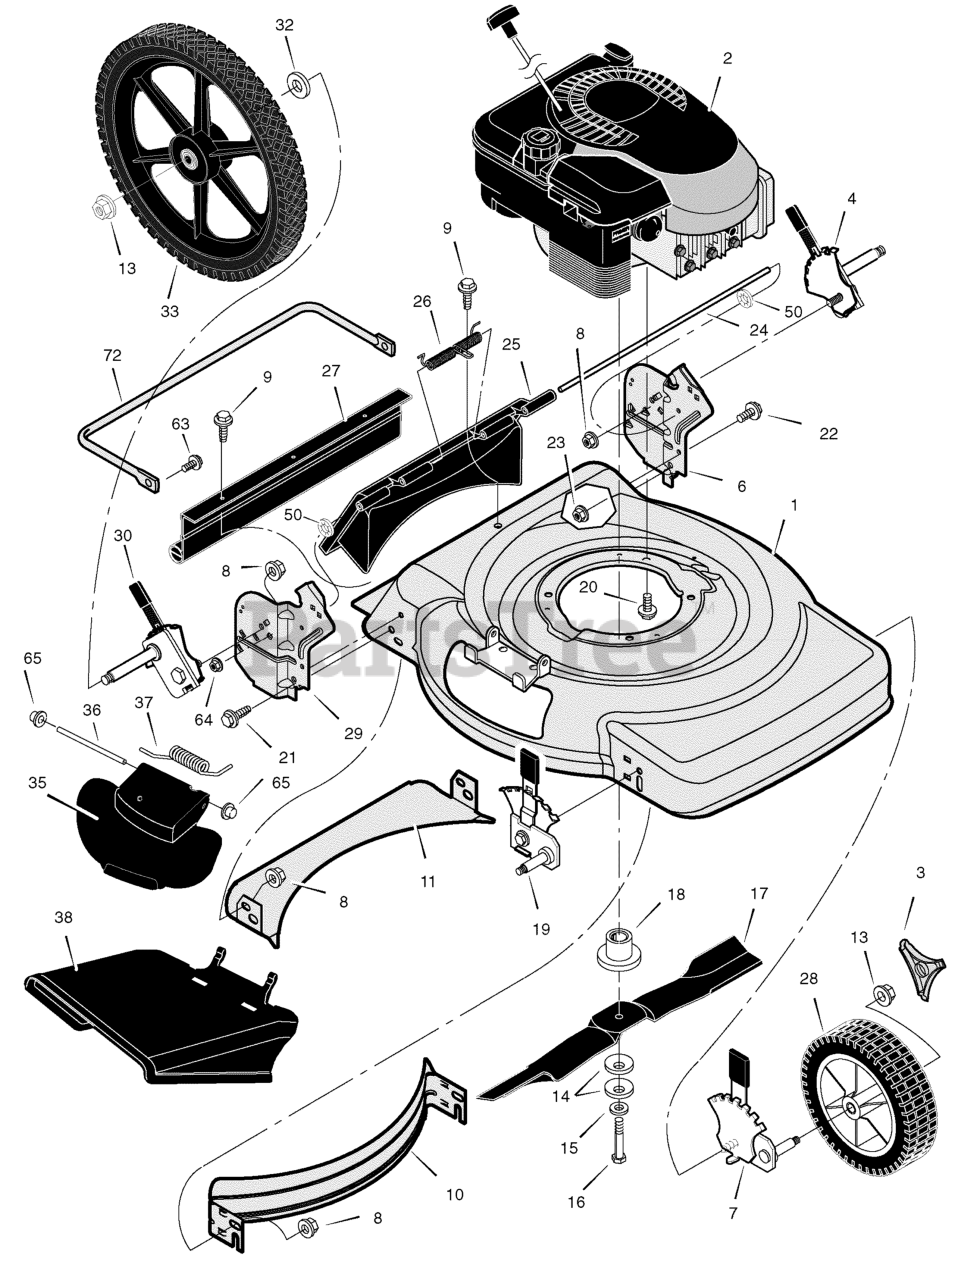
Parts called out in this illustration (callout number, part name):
1	Housing
2	Engine *
3	Cap, Hub (Gray)
4	Adjuster, Left Rear Height
6	Bracket, Left Handle
7	Adjuster, Left Front Height
8	Nut, Flange
10	Baffle, Front
11	Baffle, Rear *
13	Nut, Flange
14	Washer, Belleville
15	Washer
18	Adapter, Blade
19	Adjuster, Right Front Height
20	Bolt, Engine
21	Bolt
22	Bolt
23	Nut, Flange
24	Rod, Pivot
25	Door, Rear (Black)
25	Door, Rear (Gray)
26	Spring
27	Guard, Rear
28	Wheel & Tire (Gray)
29	Bracket, Right Handle
30	Adjuster, Right Rear Height
32	Washer
33	Wheel, Rear (Gray)
35	Cover, Mulch (Black)
35	Cover, Mulch (Gray)
36	Rod, Pivot
37	Spring, Torsion
38	Deflector, Chute (Black)
38	Deflector, Chute (Gray)
50	Retainer, Push
63	Bolt
65	Push On Cap
